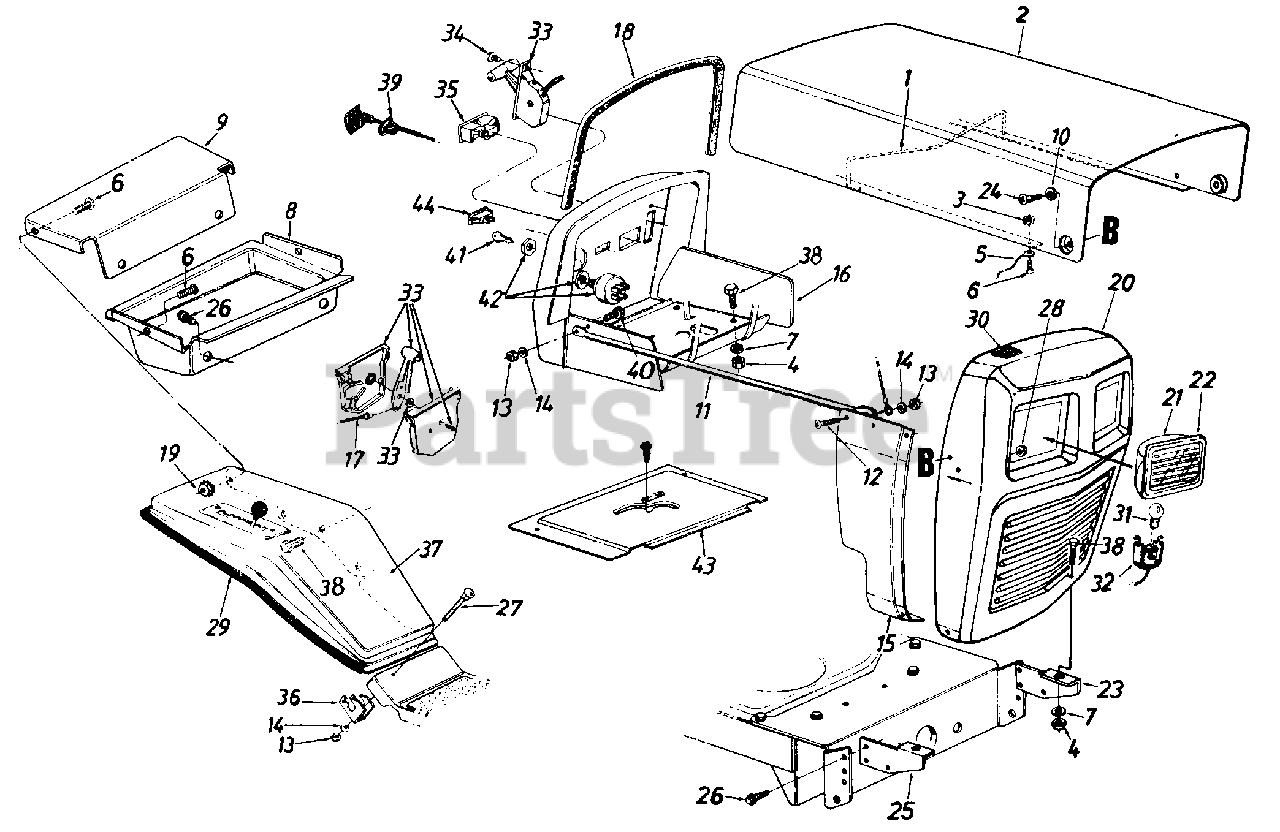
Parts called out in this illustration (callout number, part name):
1	Hood Spring
4	Hex Nut 5/16-18 Thd.
5	Hood Stop 7" Lg.
6	Truss Hd. Scr. #10-24 x 1/2"
7	L-Wash. 5/16" I.D.
8	Tool Tray
11	Grille Support Rod
12	Truss Hd. Scr. 1/4-20 x .75"
13	Hex Nut 1/4-20 Thd.
14	L-Wash. 1/4" I.D.
15	R.H.-Grille Side Panel
17	Throttle Control Wire-B&S
18	Molding Strip 27" Lg.
19	Hex Sems Nut #10-24 Thd.
22	Headlight Lens
25	Mounting Brkt.
26	Hex Wash. Hd. AB-Tap Scr. 5/16 x .75" Lg.
27	Carriage Bolt 1/4-20 x 2.0" Lg.*
28	L-Nut 1/4-28 Thd.
29	Trim Strip-57" Lg.
30	Foam Strip 3/8 x 1-1/8 x 11/2
31	Head Lamp
32	Twist Lock Lamp Socket
33	Throttle Box Ass'y.
34	Truss Mach. AB-Tap Scr. #10 x .5" Lg.
35	Ammeter
36	Fender Clamp
39	Choke Control 29" Lg.
40	Hex Bolt 1/4-20 x .62" Lg.
41	Ignition Key
42	Ignition Switch
43	Shift Cover
44	Light Switch
